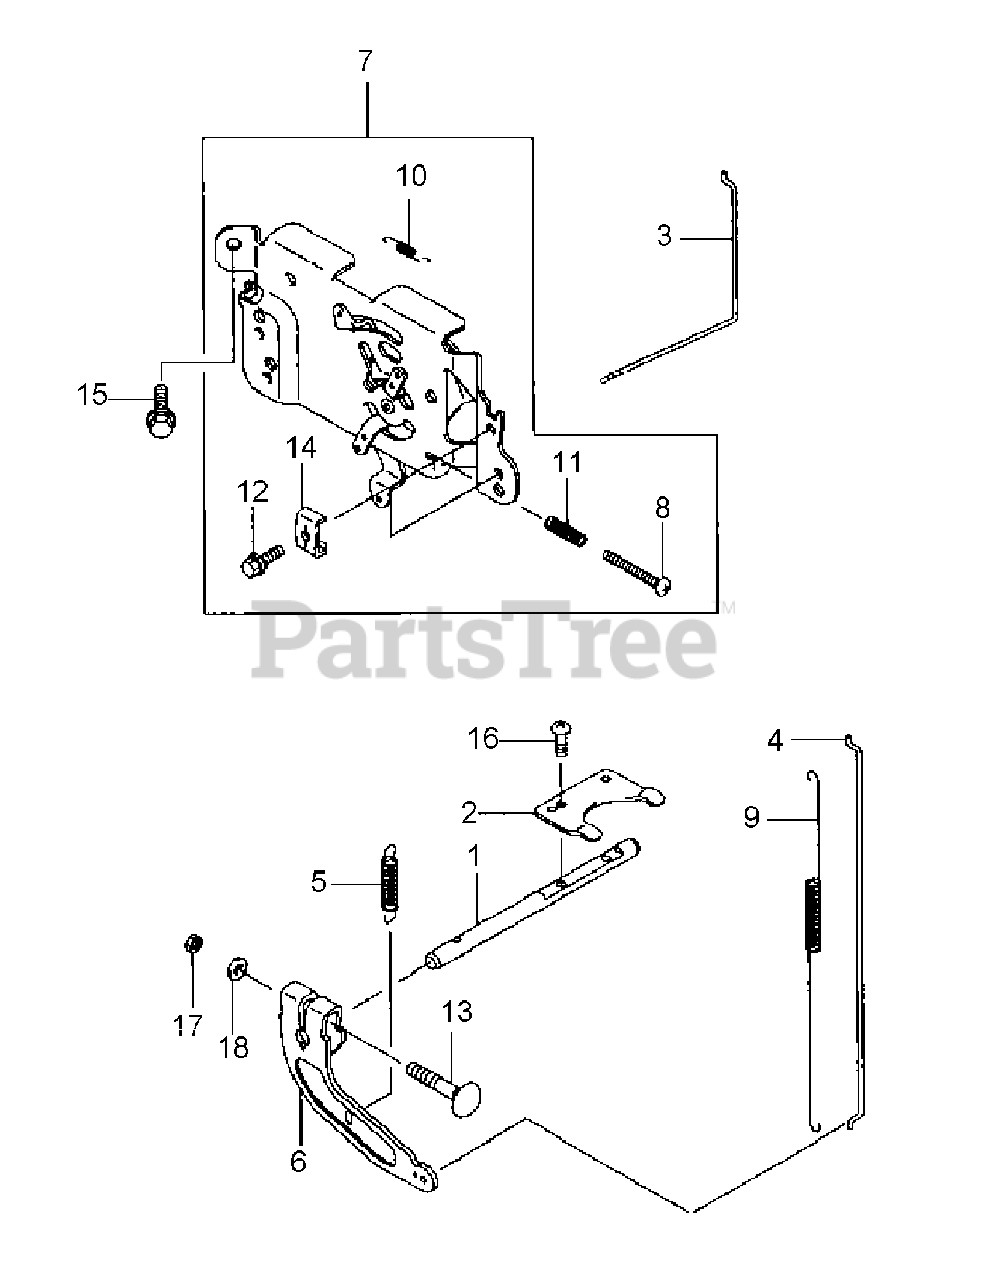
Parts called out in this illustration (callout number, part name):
5	GOVERNOR SPRING
7	CONTROL PANEL
10	SPRING
13	BOLT, 6x35
15	FLANGED BOLT
18	PLAIN WASHER
